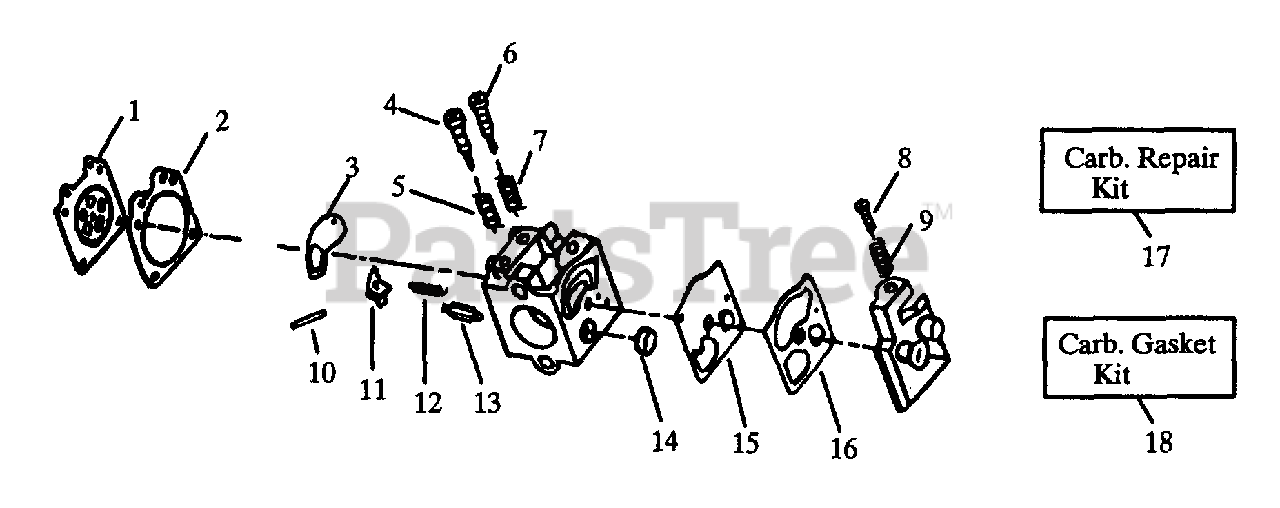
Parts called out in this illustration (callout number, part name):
1	Metering Diaphragm
2	Metering Diaphragm Gasket
3	Circuit Plate Gasket
4	Hi Speed Needle
5	Hi Speed Needle Spring
6	Idle Needle
7	Idle Needle Spring
8	Idle Speed Screw
9	Idle Speed Spring
10	Metering Lever Pin
11	Metering Lever
12	Metering Lever Spring
13	Inlet Needle Valve
14	Inlet Screen
15	Pump Diaphragm
16	Pump Gasket
17	Carb. Kwik Repair Kit
18	Carb. Gasket/Diaphragm Kit
